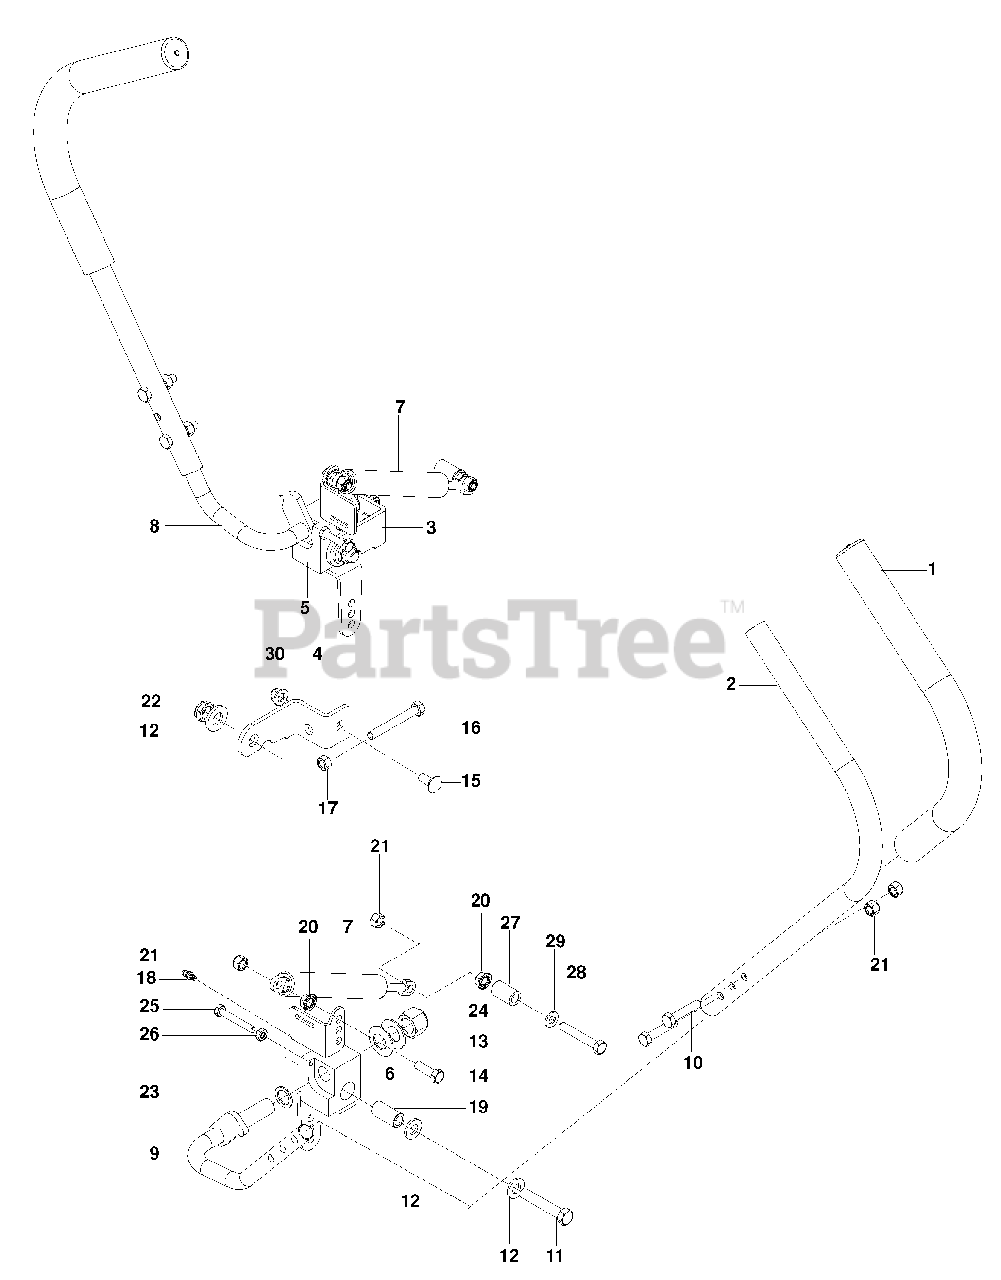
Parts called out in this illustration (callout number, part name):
2	LEVER, UPPER
3	STOP, STEER CNTRL RH
4	STOP, STEER CNTRL LH
8	LOWER LEVER, RH
9	LOWER LEVER, LH
10	HCS 5/16-18 x 1 1/2
11	HCS 1/2-13 x 2 3/4
12	WASHER 1/2 SAE
13	WASHER 5/8 BELLEVILLE
14	HCS 5/16-18 x 1
15	RHSNB 5/16-18 x 3/4
16	BOLT, HEX 5/16-18 x 2 1/2 TPBLT
17	NUT, 5/16-18 HEX
18	ZERK
19	BUSHING 1/2 ID x 3/4 OD
20	NUT 5/16-18 HEX WHIZLK
21	NUT 5/16-18 HEX NYLOC
22	NUT 1/2-13 JAM NYLOC GR 2
23	WASHER, SPECIAL
24	NUT 5/8-11 NYLOC
25	HCS 1/4-20 x 1 3/4
26	NUT 1/4-20 JAM
28	HCS 5/16-18 x 2
29	WASHER 5/16 SAE FLT
30	NUT 5/16-18 FLG HEX NYLOC
